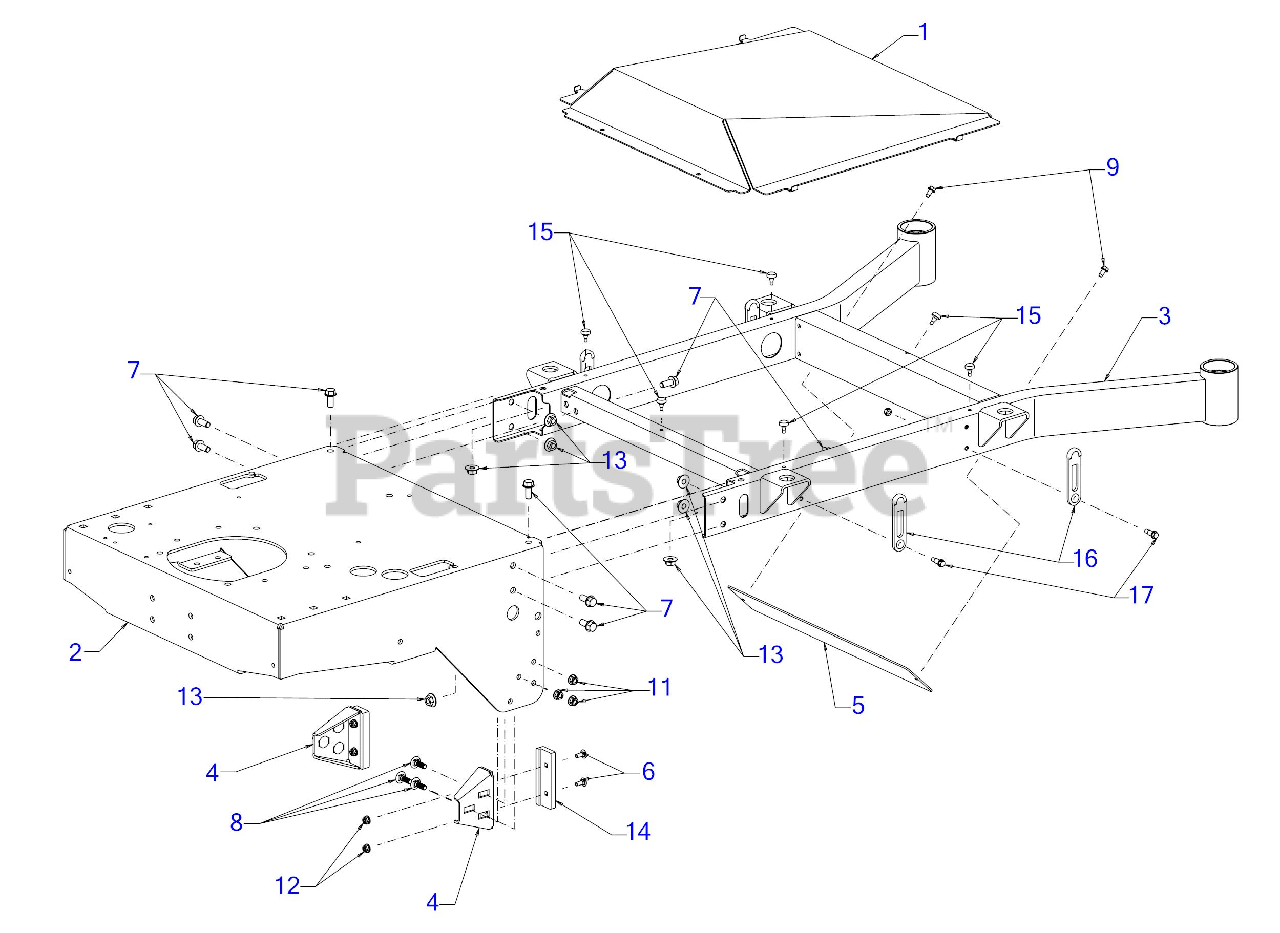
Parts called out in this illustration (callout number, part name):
6	CARRIAGE BOLT 1/4-20 x .62
7	SCREW 3/8-16 x .875 GR5
8	SCREW 5/16-18 x 1.00 GR5
9	SCREW 1/4-20 X.500
10	HEX NUT
11	FLANGE LOCK NUT 5/16-18
12	FLANGE LOCK NUT
13	FLANGE LOCK NUT
14	BUMPER PAD
15	RUBBER BUMPER
16	COVER STRAP 2.50 LONG
17	SHOULDER SCREW
